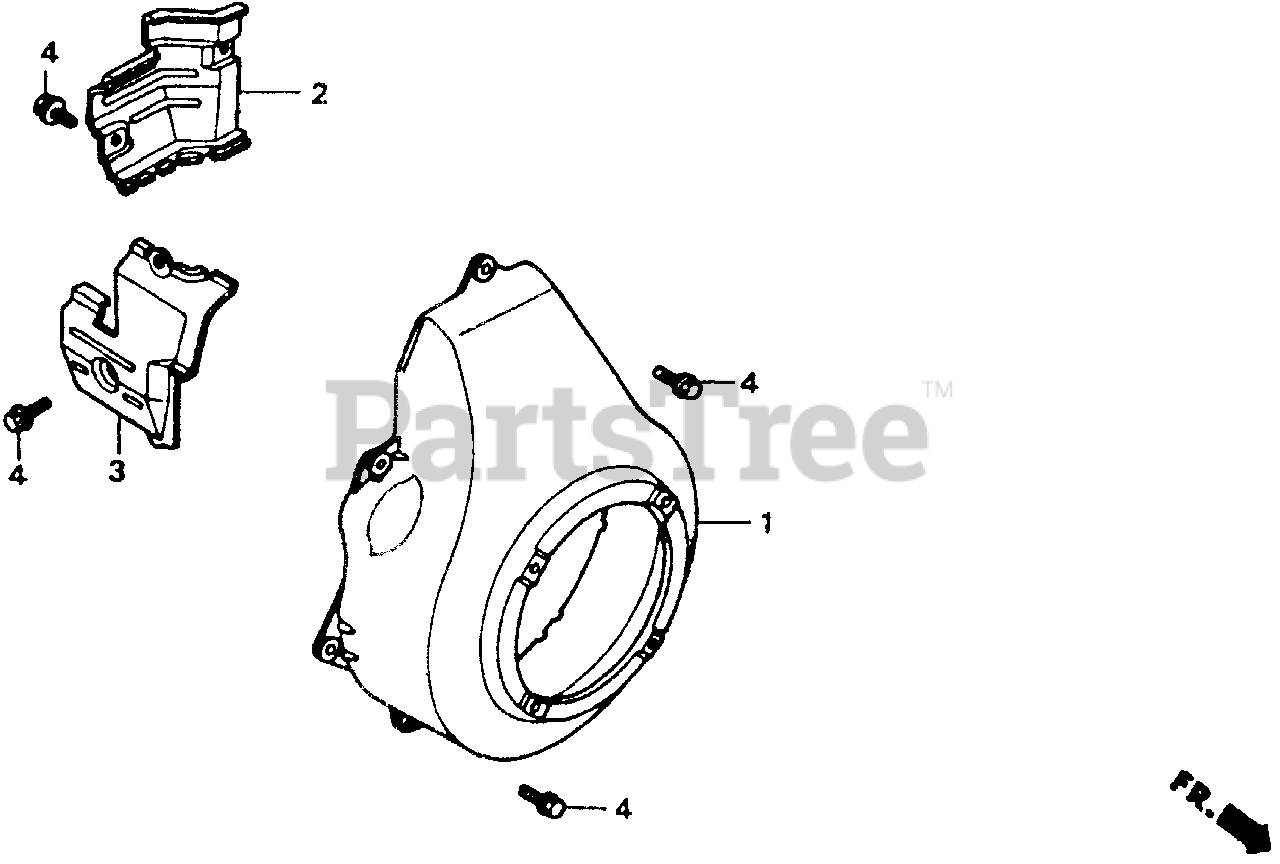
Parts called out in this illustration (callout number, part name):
1	COVER, FAN *NH116M* (URBAN SILVER METALLIC)
2	SHROUD (A)
3	SHROUD (B)
4	BOLT, FLANGE (6X12)
